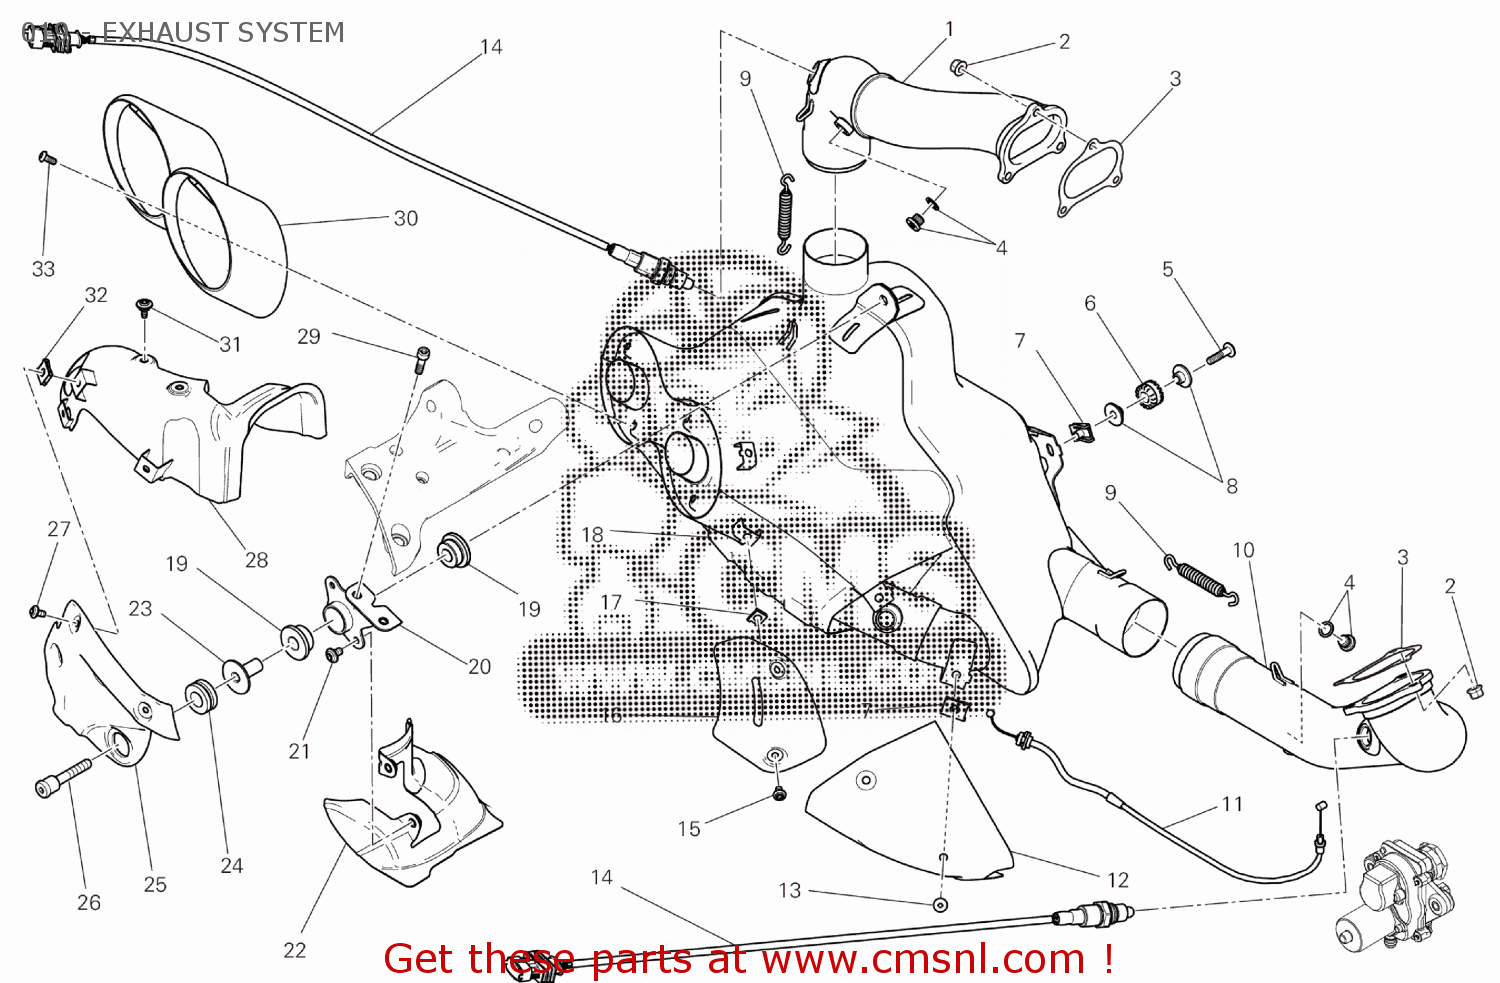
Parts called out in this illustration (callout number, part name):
1	EXHAUST MANIFOLD
2	NUT
3	GASKET, EXHAUST PIPE
4	PLUG ASSY
5	SCREW TBEIF M6X25
6	VIBRATION DAMPER PAD
7	QUICK FASTENING
8	SPACER 6.25X10X5.75
9	COMPLETE SPRING
10	HORIZONTAL HEAD EXHAUST PIPE
11	CABLE, EXHAUST VALVE
12	COVER
13	SCREW
14	SENSOR LAMBDA SOND
15	SCREW
16	HEAT GUARD
17	QUICK FASTENING M5
18	SILENCER
19	VIBRATION DAMPER PAD
20	BRACKET, SILENCER
21	SCREW M6X10
22	HEAT GUARD
23	SPACER
24	VIBRATION DAMPER PAD
25	HEAT GUARD VERTICAL
26	SCREW, SPECIAL
27	SCREW TBEI M5X10
28	HEAT GUARD VERTICAL
29	SCREW M6X22
30	BAFFLE
31	SCREW M5X9
32	QUICK FASTENING
33	SCREW M5X12
